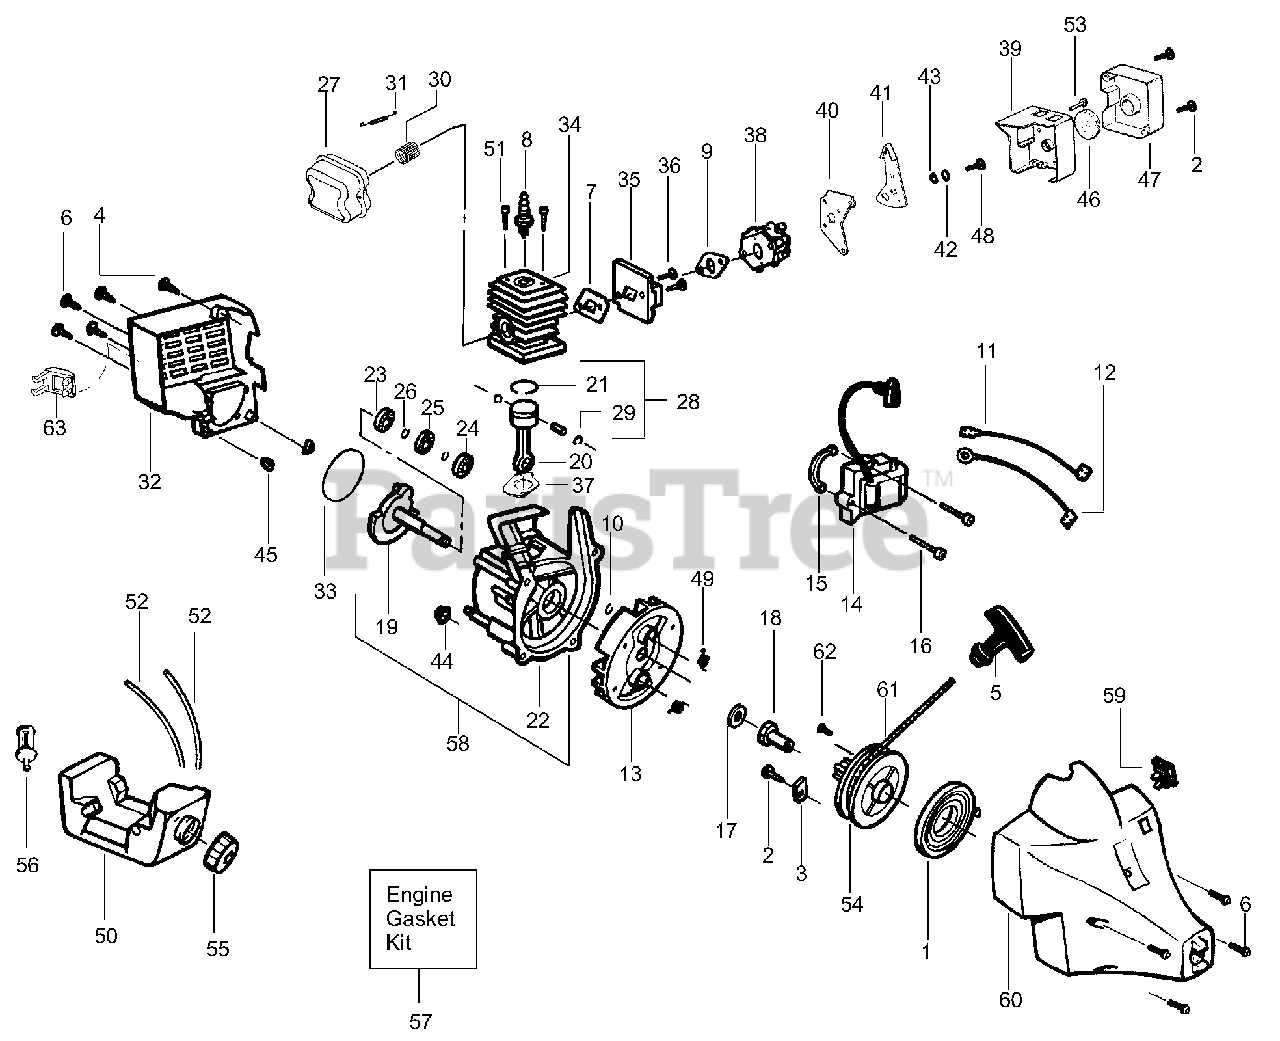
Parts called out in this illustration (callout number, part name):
1	Starter Spring
3	Retainer Can
4	Screw-Shrd/Fan Hsg.
5	Starter Handle
6	Screw
7	Gasket-Cylind./Carb.
8	Spark Plug (RCJ 8Y)
9	Gasket-Carb.
10	Retainer Ring-C'shaft
11	Assy-Lead Wire
12	Assy-Ground Wire
13	Assy-Flywheel
14	Module-Ignition
15	Spacer-Module
16	Screw-Module
17	Washer-Flat
18	Coupling-Coupling
19	Assy-Crankshaft
20	Assy-Connecting Rod
21	Piston Ring
22	Assy-Crankcase
23	Inner Bearing
24	Outer Bearing
25	C'case Seal
26	Retain. Ring-C'shaft
27	Kit-Muffler
28	Kit-Piston
29	Retainer-Piston Pin
30	Kit-Spark Arrestor
31	Spring-Muffler
32	Shroud-Rear
33	O-Ring/Gasket-C'case
34	Kit-Cylinder
35	Kit-Carb. Adaptor
37	Gasket-Cylinder
38	Kit-Carburetor Ass'y
40	Choke Plate Mounting
41	Choke Lever
42	Spacer-Choke
44	Isolator-C'Case
45	Isolator-Shroud
46	Foam-Air Filter
47	Cover-Air Filter
49	Spring-Starter Dog
50	Assy-Fuel Tank
51	Screw-Cylinder
52	Kit-Fuel Line
54	Kit-Starter Pulley
55	Assy-Fuel Cap
56	Assy-Fuel Pickup
57	Kit-Engine Gasket
58	Assy-C'case & C'shaft
59	Switch-Momentary
60	Assy-Fan Housing
61	Kit-Rope
63	Guard-Muffler
